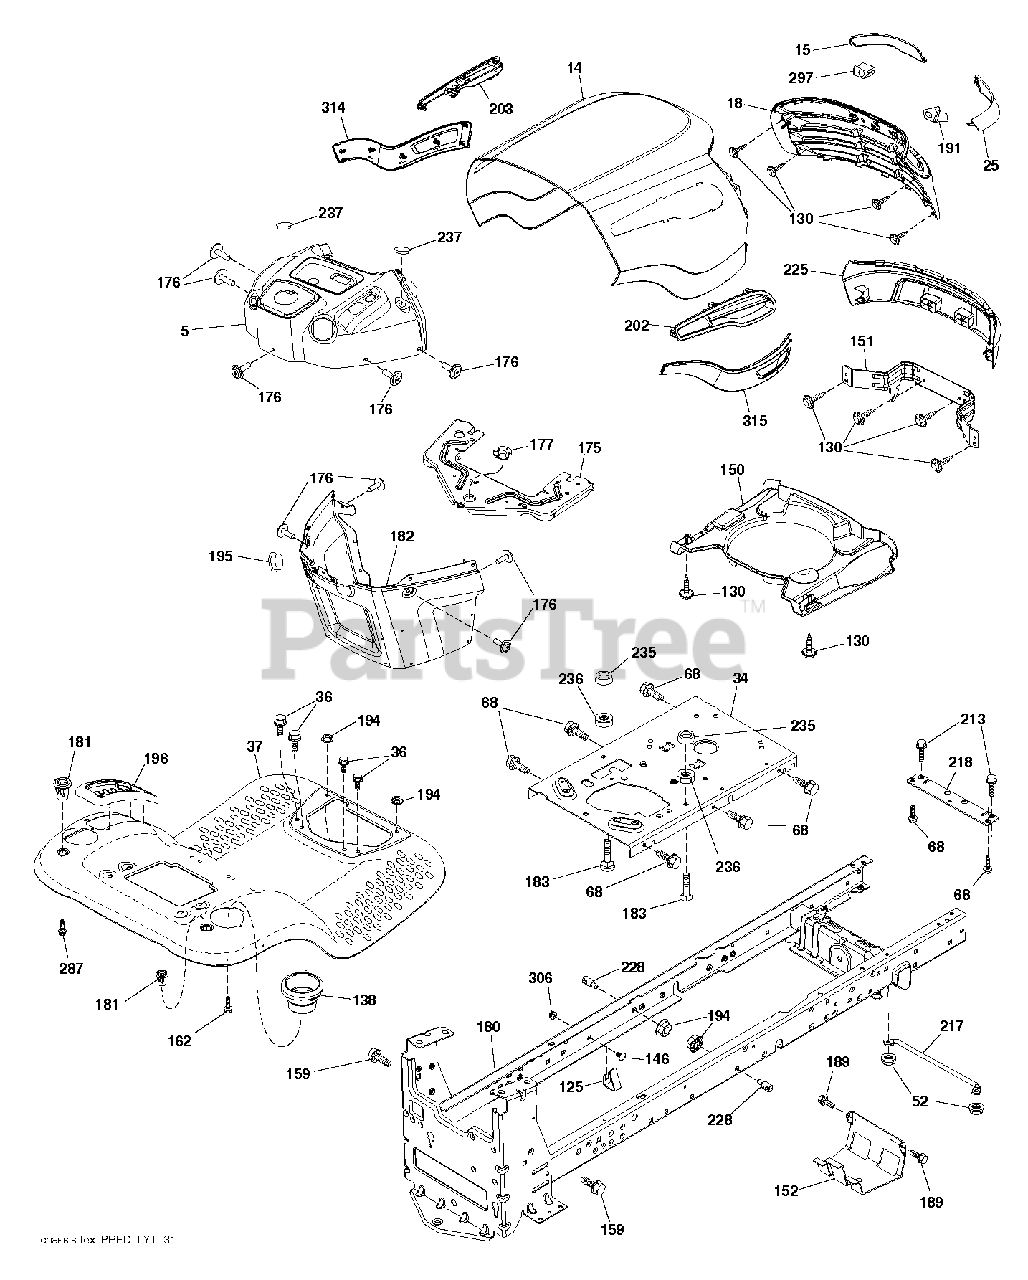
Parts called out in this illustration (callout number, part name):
36	SCREW 5/16"
52	LOCKNUT
125	Fuel Line Clip
130	SCREW.#10 X 0.750.BOS THREAD
138	CUPHOLDER.TL.TEX.BLACK
146	BOLT.RDHD.SHT.SQNK.3
150	PREDATOR.YT.GT.HOOD.A
152	SHIELD BROWNING
159	SCREW, 3/8-16X3/4
162	SCREW.HI-LO.CONSOLE
175	PLATE.CROSSMEMBER.HUSQ
176	SCREW.#10-24X5/8.RN.QU
177	BUSHING STEERING
180	CHASSIS
181	FEND/FTRST.PCH.CPH.NFW
182	DASH.LOWER.COMMON.12V.ADAPTOR
183	BOLT.5/16-18X1-1/4 FULL THD
189	SCREW
194	NUT LOCK HEX FLANGE 5/16-18
195	PLUG.HOLE.DASH.LOWER.12V.BLK
196	CONSOLE.ASM.DECKLFT.BL/RBT.TLT
202	VENT.SIDE.RH.PRED2.GTYT.JONS
203	VENT.SIDE.LH.PRED2.GTYT.JONS
213	BOLT
217	ROD.PIVOT.HOOD
218	X-PIECE.HOOD.STOP.NON/
228	STUD.FASTNER.W/ANTI-ROTATE
235	SPACER FENDER
236	NUT.CENTERLOCK.5/16-
237	PLUG.MOUNT.CARGO.BLK
306	NUT LOCK FLG 3/8-16 UNC
314	TRIM.SIDE.GT/YT/PRED2.LH.BL
315	TRIM.SIDE.GT/YT/PRED2.RH.BL
